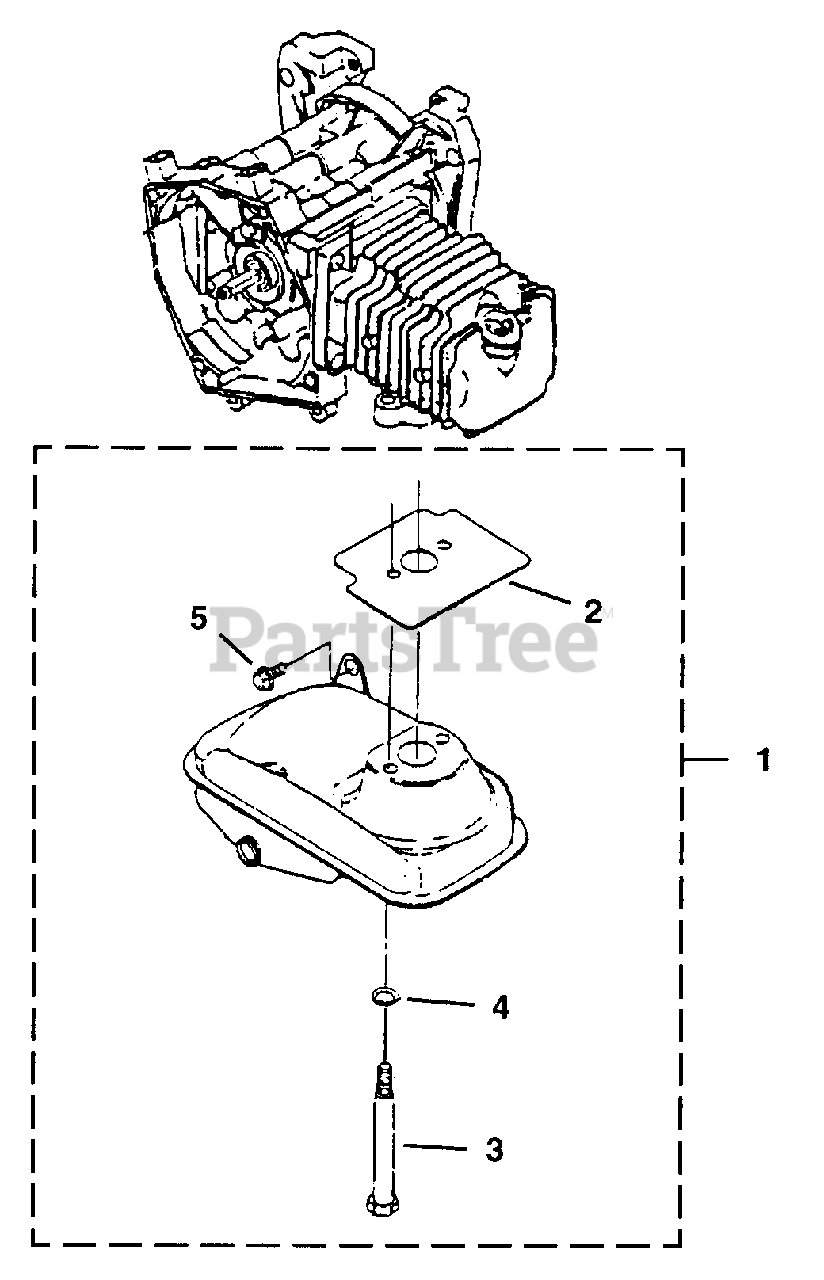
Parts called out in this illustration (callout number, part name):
1	MUFFLER ASSEMBLY
2	GASKET-Muffler
3	BOLT-Muffler. (M6 x 13)
4	WASHER (M6)
5	BOLT ASSEMBLY (M6 x 16 W SW)
